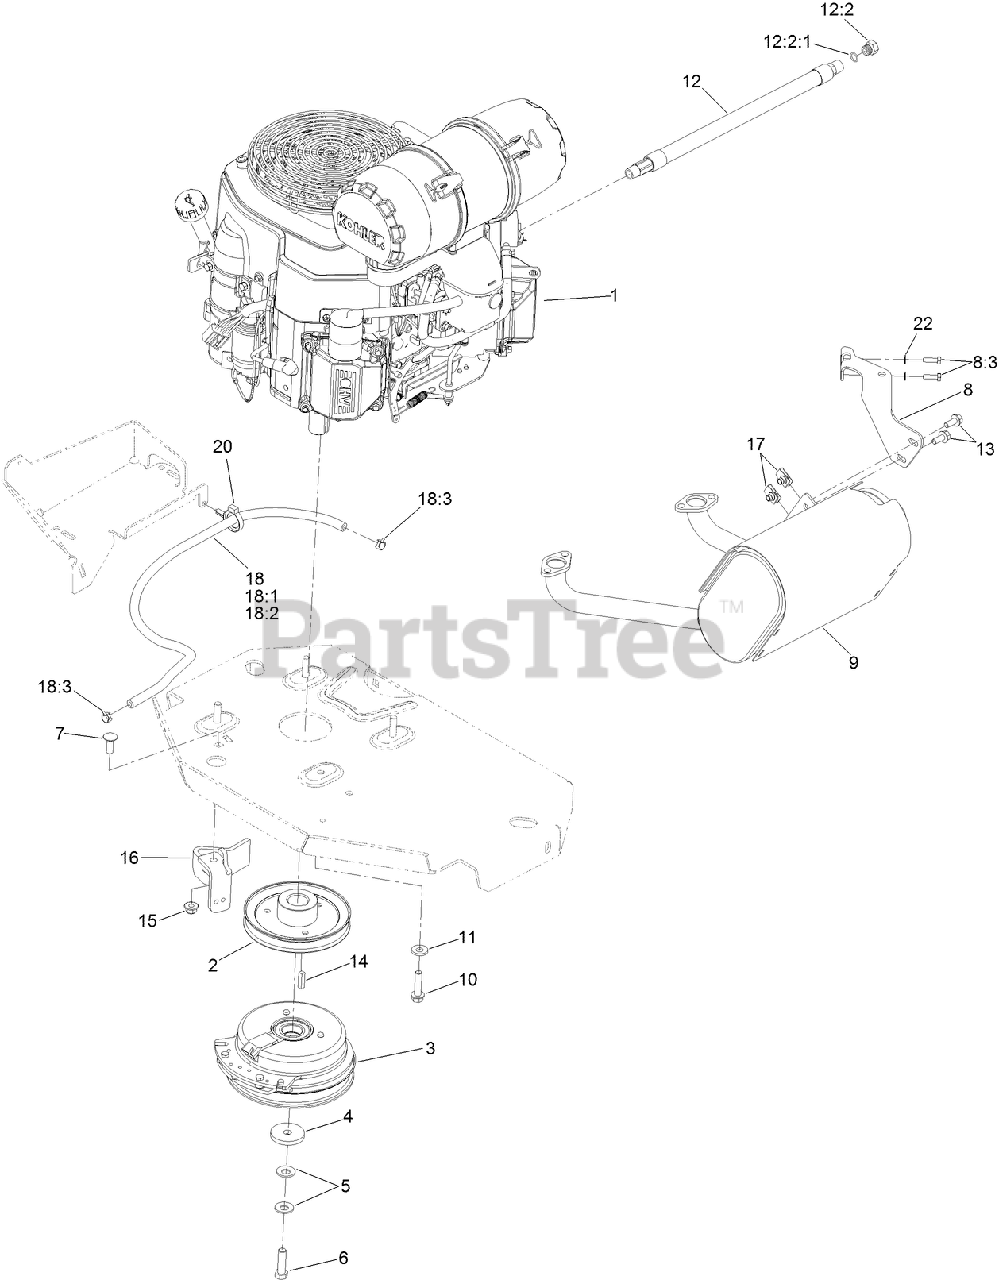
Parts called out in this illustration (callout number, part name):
2	SHEAVE
3	CLUTCH KIT
4	WASHER-CLUTCH
5	WASHER-SPRING
6	SCREW-HH
7	SCREW-CARR
8	MUFFLER BRACKET KIT
8:3	SCREW-HH
9	MUFFLER--KIT
10	SCREW-HWH
11	WASHER-BELLEVILLE
12	OIL DRAIN HOSE ASM
12:2	PLUG-HH
12:2:1	O-RING
13	SCREW-HHF
15	NUT-HF, NI
16	CLUTCH-ANCHOR
17	NUT-U
18	FUEL LINE ASM
18:1	HOSE-FUEL
18:2	SLEEVE-THERMAL
18:3	CLAMP-HOSE
20	CLAMP-HOSE
22	WASHER-SPRING
